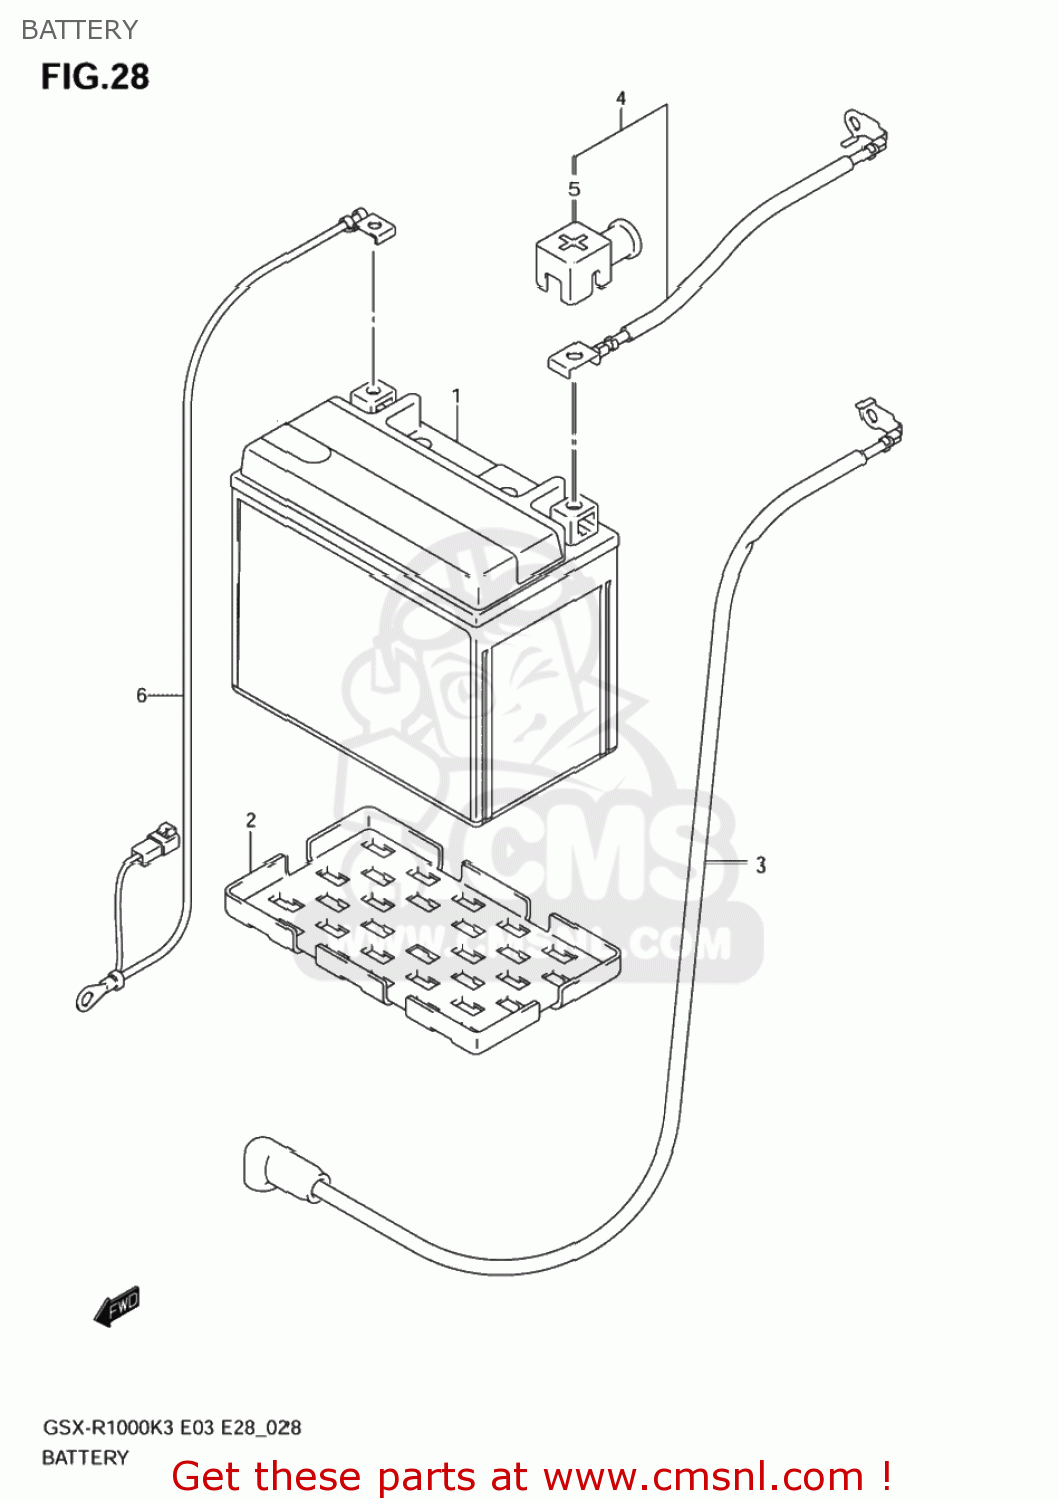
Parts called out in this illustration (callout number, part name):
1	BATTERY ASSEMBLY (12V) FTX
2	PROTECTOR,BATTERY
3	WIRE,STARTER MOTOR LEAD
4	WIRE,BATTERY PLUS LEAD
5	CAP,BATTERY PLUS
6	WIRE,BATTERY MINUS LEAD
